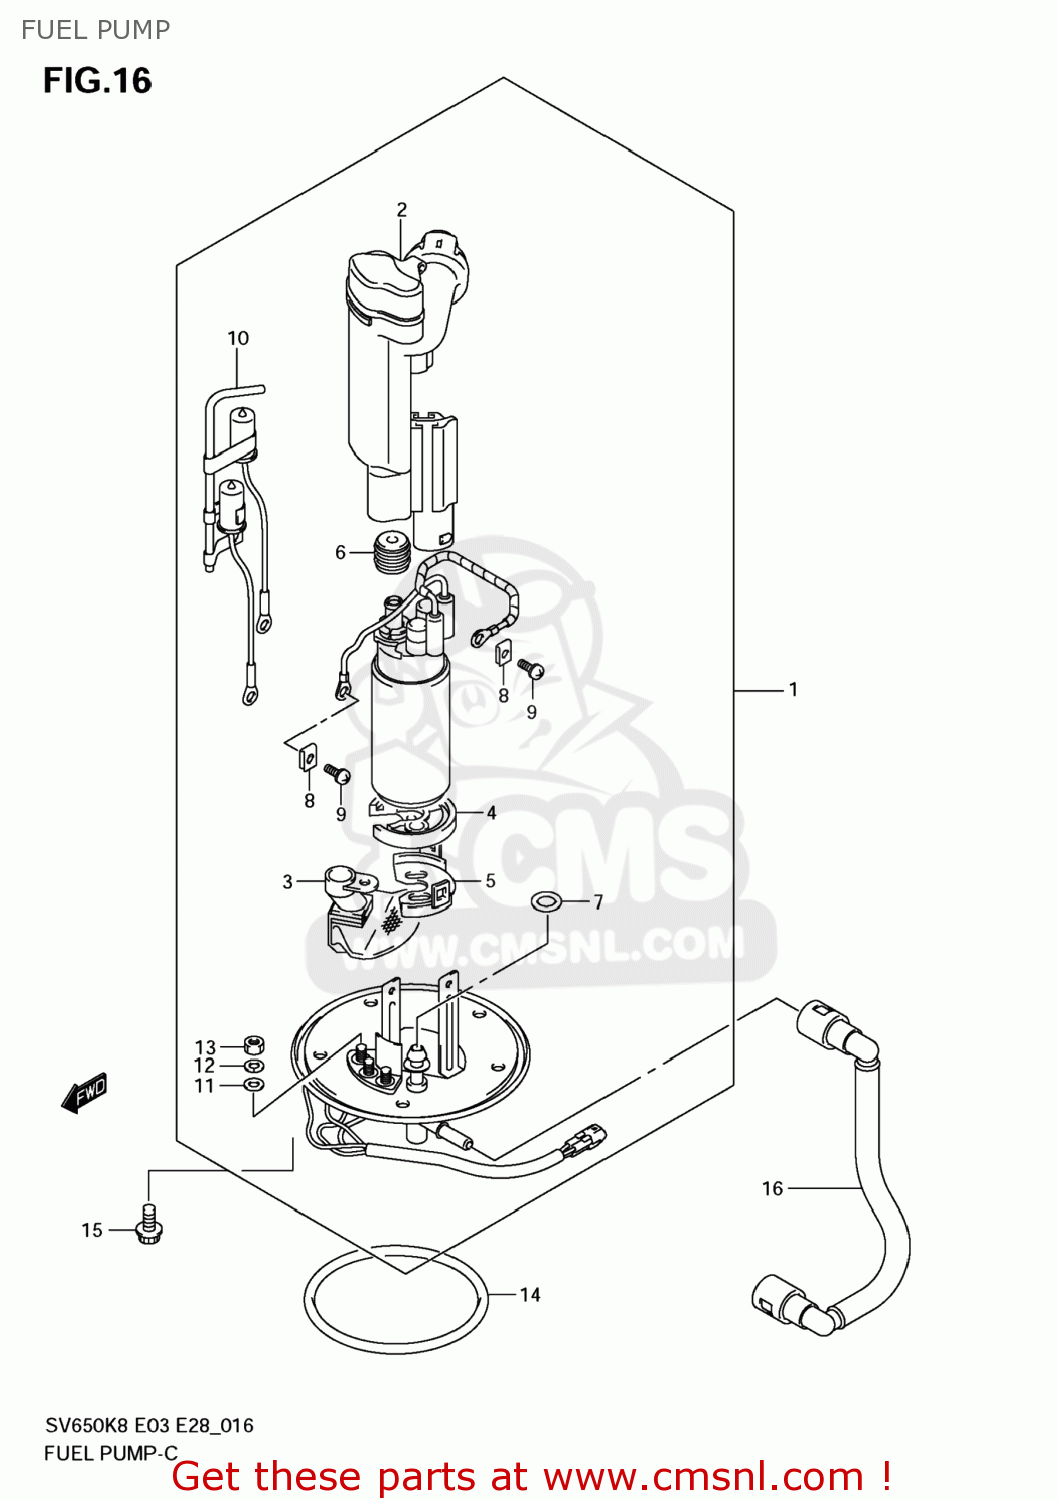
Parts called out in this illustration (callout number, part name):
1	PUMP ASSY,FUEL
2	FILTER,FUEL
3	STRAINER,FUEL PUMP
4	CUSHION
5	HOLDER,FUEL PUMP
6	BUSH,FUEL PUMP
7	O RING
8	NUT
9	SCREW
10	THERMISTOR
11	WASHER
12	WASHER,SPRING
13	NUT
14	O RING,FUEL PUMP
15	BOLT
16	HOSE COMP,FUEL
